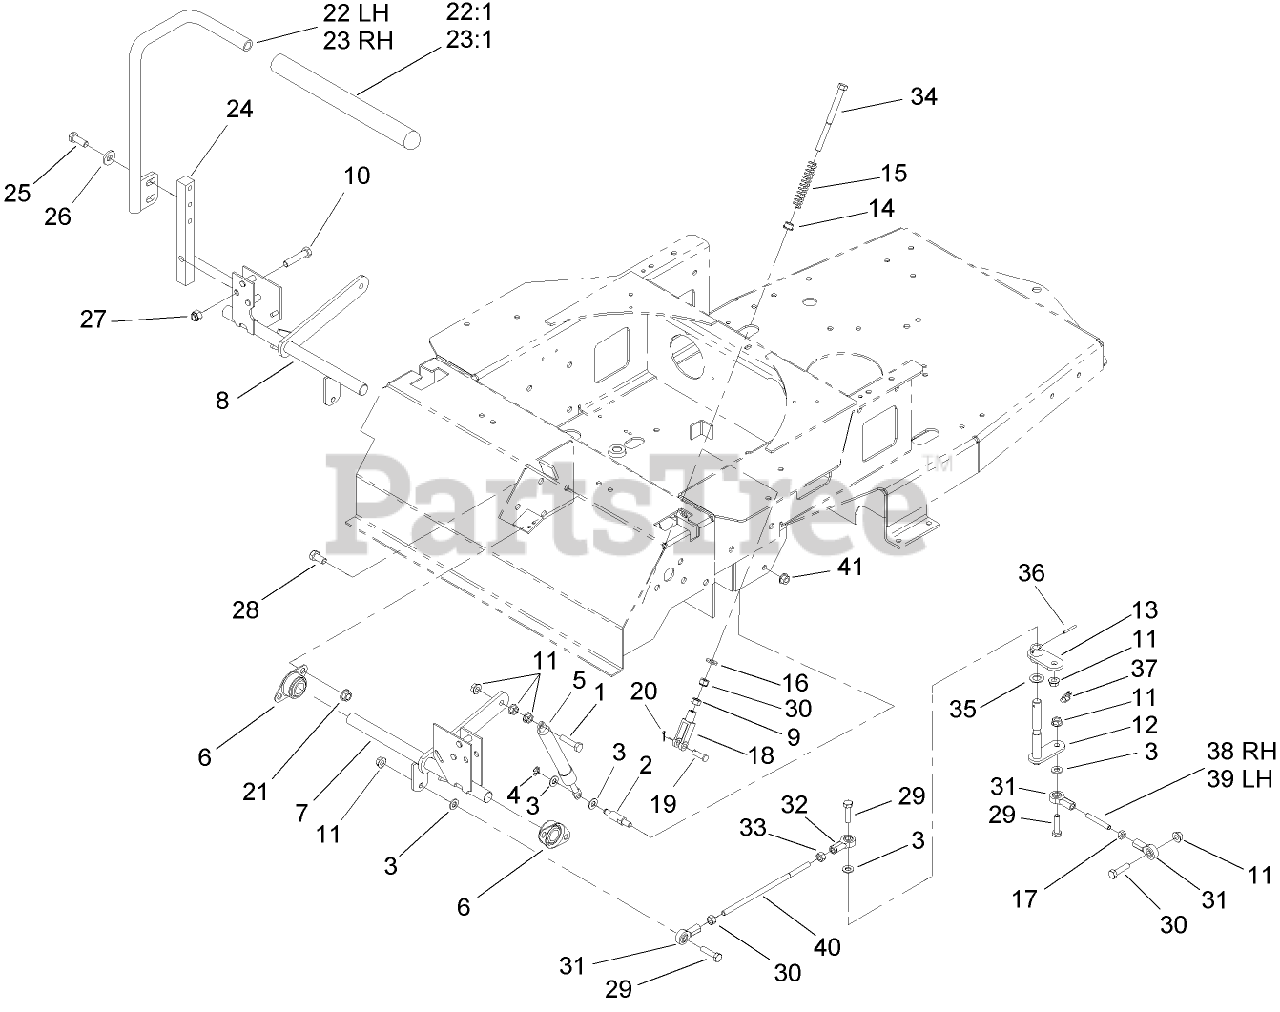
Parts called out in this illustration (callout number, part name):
1	SCREW-HH
2	PIN-DAMPER
3	WASHER-PLAIN
4	RING-RETAINING, EXT
6	BEARING-FLANGE, SIDE
7	BRACKET-MOTION CONTROL, LH
8	BRACKET-MOTION CONTROL, RH
9	NUT-LOCK
10	SCREW-HH
11	NUT-HF
12	PIVOT ASM
13	PIVOT PLATE ASM
14	BUSHING-FLANGED
15	SPRING-RETURN, NEUTRAL
16	WASHER-FLAT
17	NUT-JAM
18	YOKE-ADJUSTABLE
19	PIN-CLEVIS
20	PIN-COTTER
21	NUT-HHF, WHIZ
22	LH LEVER ASM
22:1	GRIP-CONTROL, MOTION
23	RH LEVER ASM
23:1	GRIP-CONTROL, MOTION
24	ARM-SHAFT, CONTROL
25	SCREW-HH
26	WASHER-BELLEVILLE
27	NUT-LOCK, NI
28	SCREW-HH
29	SCREW-HH
30	NUT-HEX
31	BALLJOINT-RH
32	BALLJOINT-LH
34	BOLT-RETURN, NEUTRAL
35	WASHER
36	PIN-ROLL
37	FITTING-LUBE, 45 DEG
38	LINKAGE-LOWER, RH
39	LINKAGE-LOWER, LH
40	LINKAGE-UPPER
41	NUT-HF
